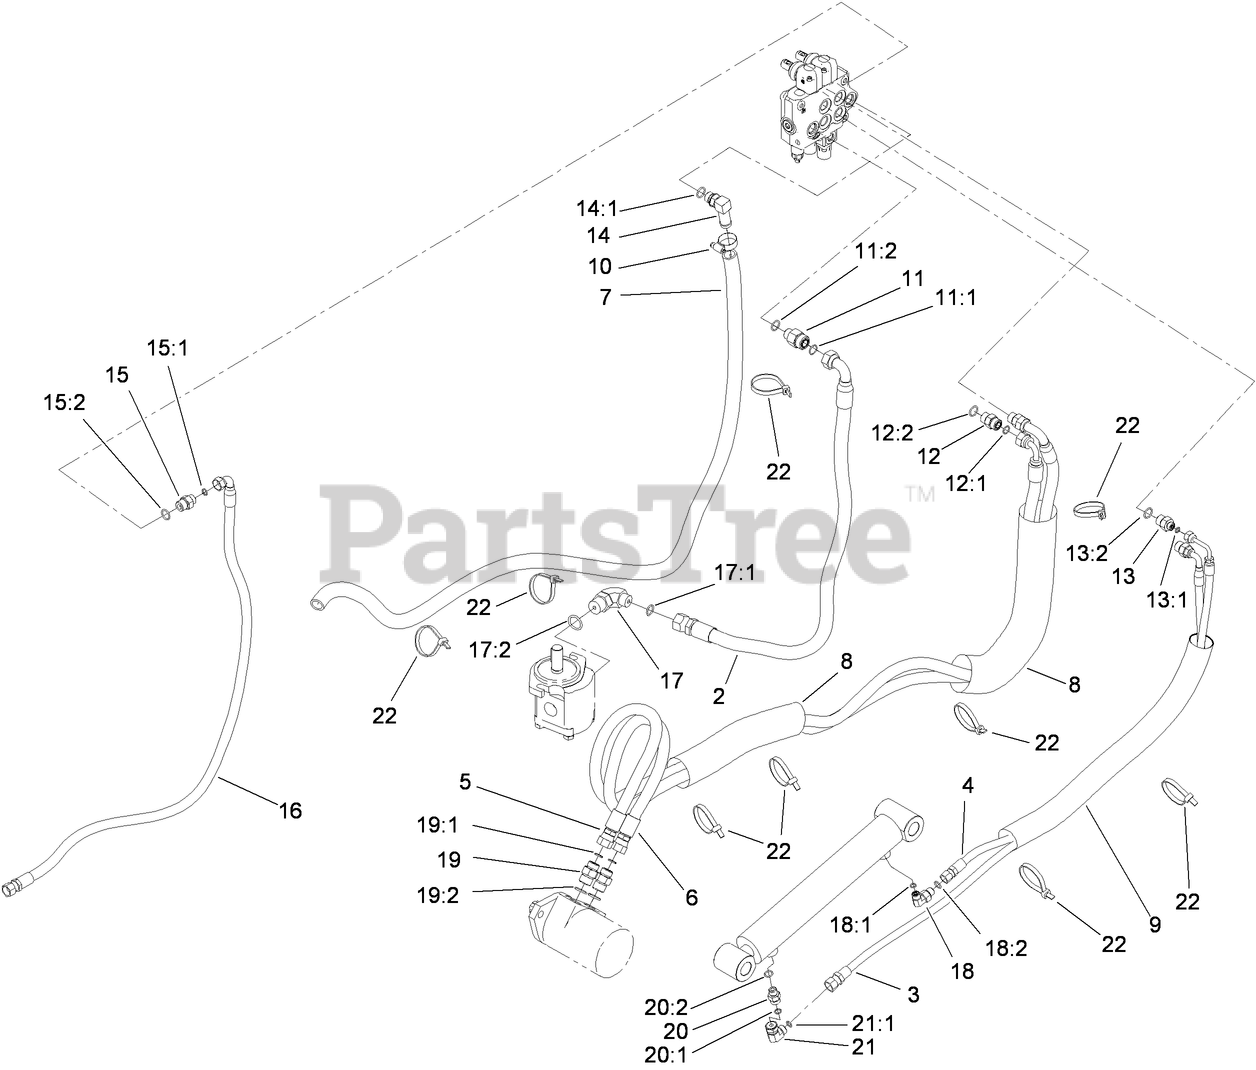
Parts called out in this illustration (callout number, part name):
2	HOSE-HYD
3	HOSE-HYD
4	HOSE-HYD
5	HOSE-HYD
6	HOSE-HYD
7	HOSE-RETURN
8	SLEEVE-PROTECTIVE
9	SLEEVE-PROTECTIVE
10	CLAMP-HOSE
11	FITTING-STR
11:1	O-RING
11:2	O-RING
12	FITTING-STRAIGHT
12:1	O-RING
12:2	O-RING
13	FITTING-STR
13:1	O-RING
13:2	O-RING
14	FITTING-ELB 90
14:1	O-RING
15	FITTING-STRAIGHT
15:1	O-RING
15:2	O-RING
16	HOSE-HYD
17	FITTING-ELBOW 90
17:1	O-RING
17:2	O-RING
18	FITTING-ELBOW 90
18:1	O-RING
18:2	O-RING
19	FITTING-STRAIGHT
19:1	O-RING
19:2	O-RING
20	VALVE-CHECK
20:1	O-RING
20:2	O-RING
21	FITTING-HYD, 90 DEG
21:1	O-RING
22	TIE-CABLE
